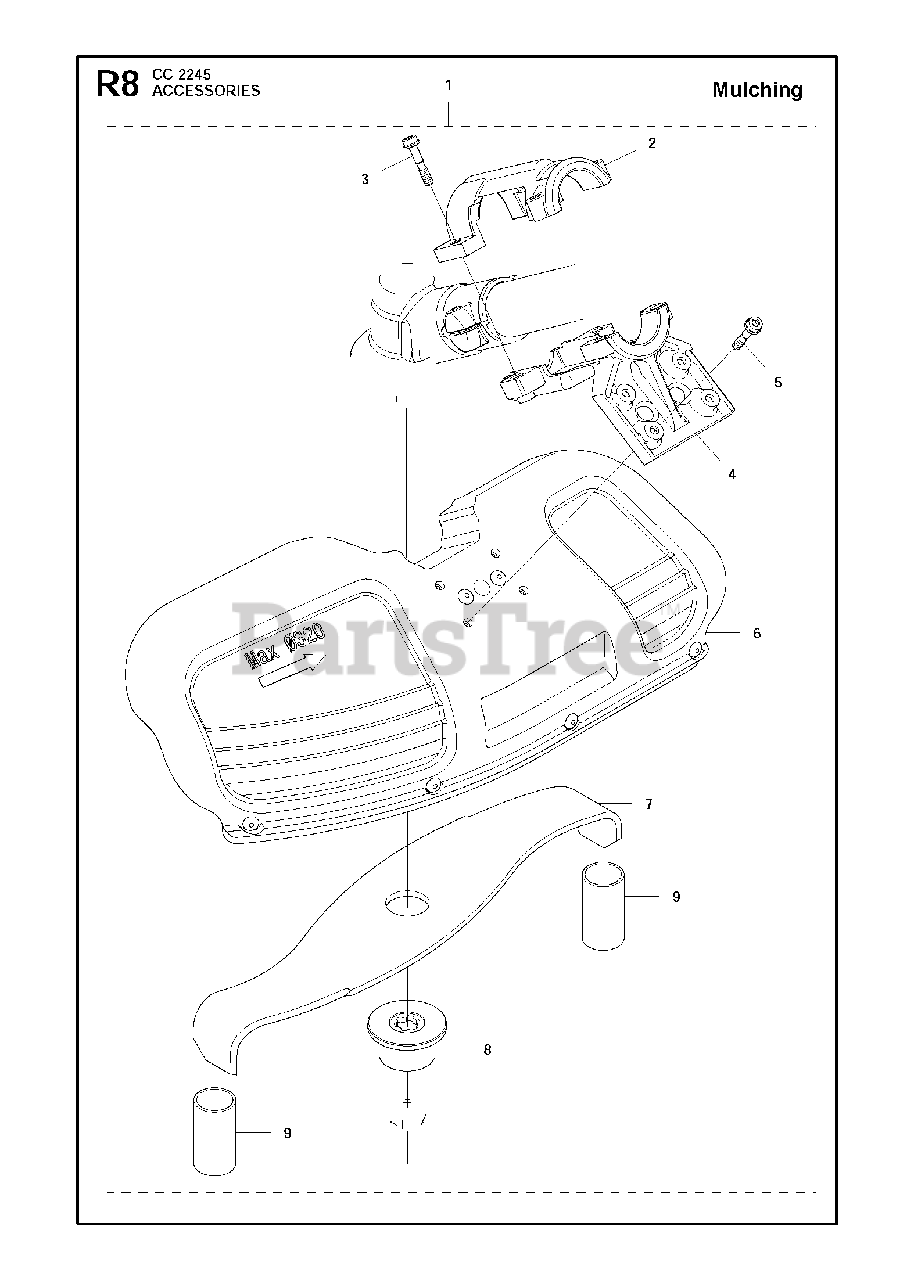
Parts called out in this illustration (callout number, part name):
2	CLAMP
3	SCREW IHSCFMO
4	BRACKET
5	SCREW IHSCFMO
6	SPRAY GUARD ASSY
7	BLADE NOT AVAIL IN US
8	SUPPORT FLANGE
9	TRANSPORT GUARD
